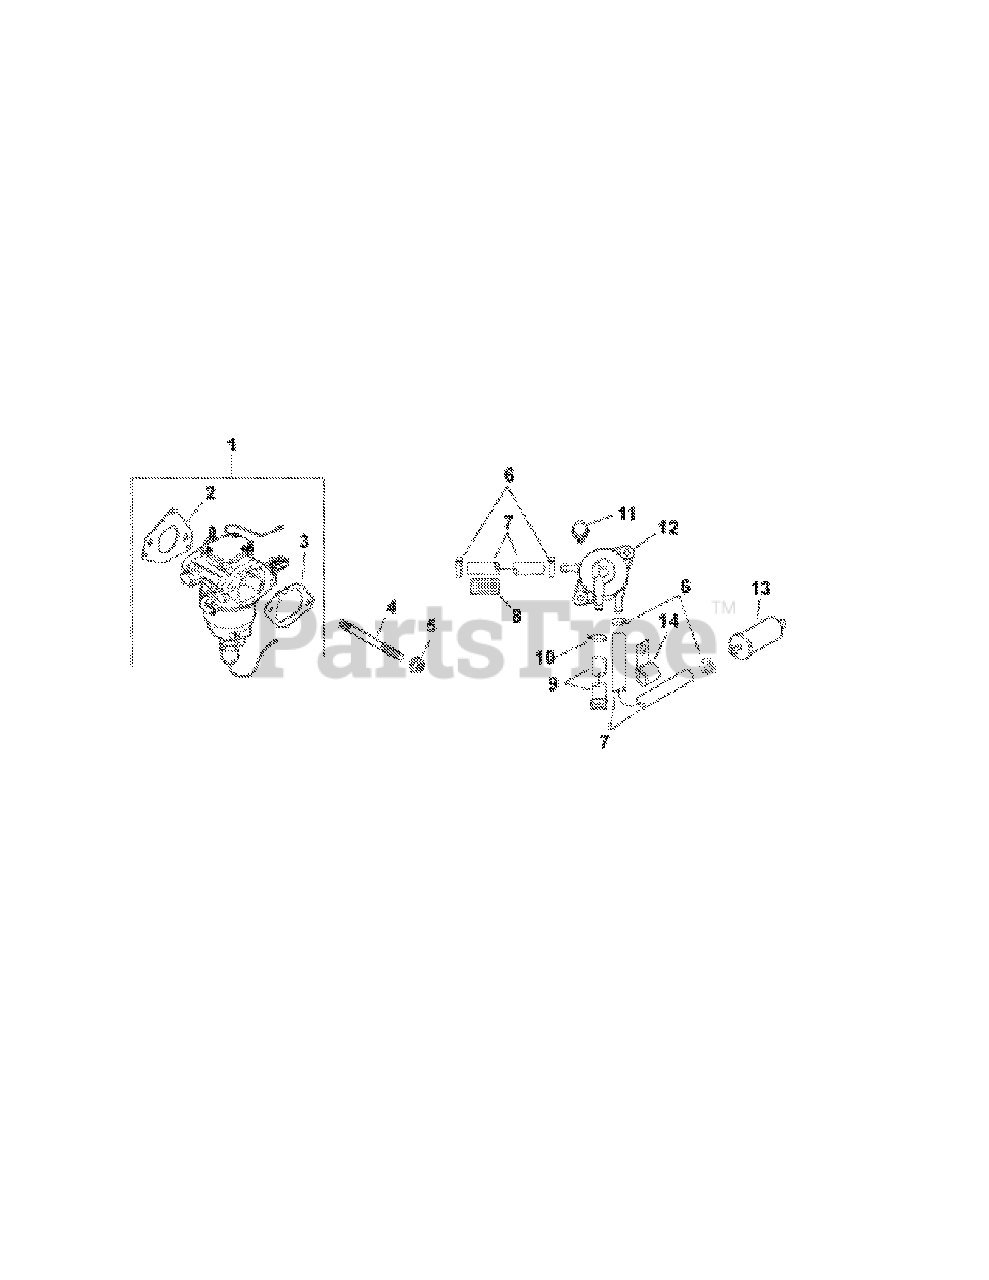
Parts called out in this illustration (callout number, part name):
1	KIT, CARBURETOR W/GASKETS
2	GASKET, CARBURETOR
3	GASKET, AIR CLEANER BASE
4	STUD, M6X1.0X106
5	NUT, FLG M6X1.0
6	CLAMP, SPRING HOSE 1/2"
7	LINE, FUEL (24"-CUT TO LENGTH)
8	SLEEVE, ANTI ABRASION
9	KIT, FUEL PUMP HOSE W/CLAMP
10	CLAMP, HOSE
11	SCREW, TAP M6X1.7X18
13	FILTER, FUEL
